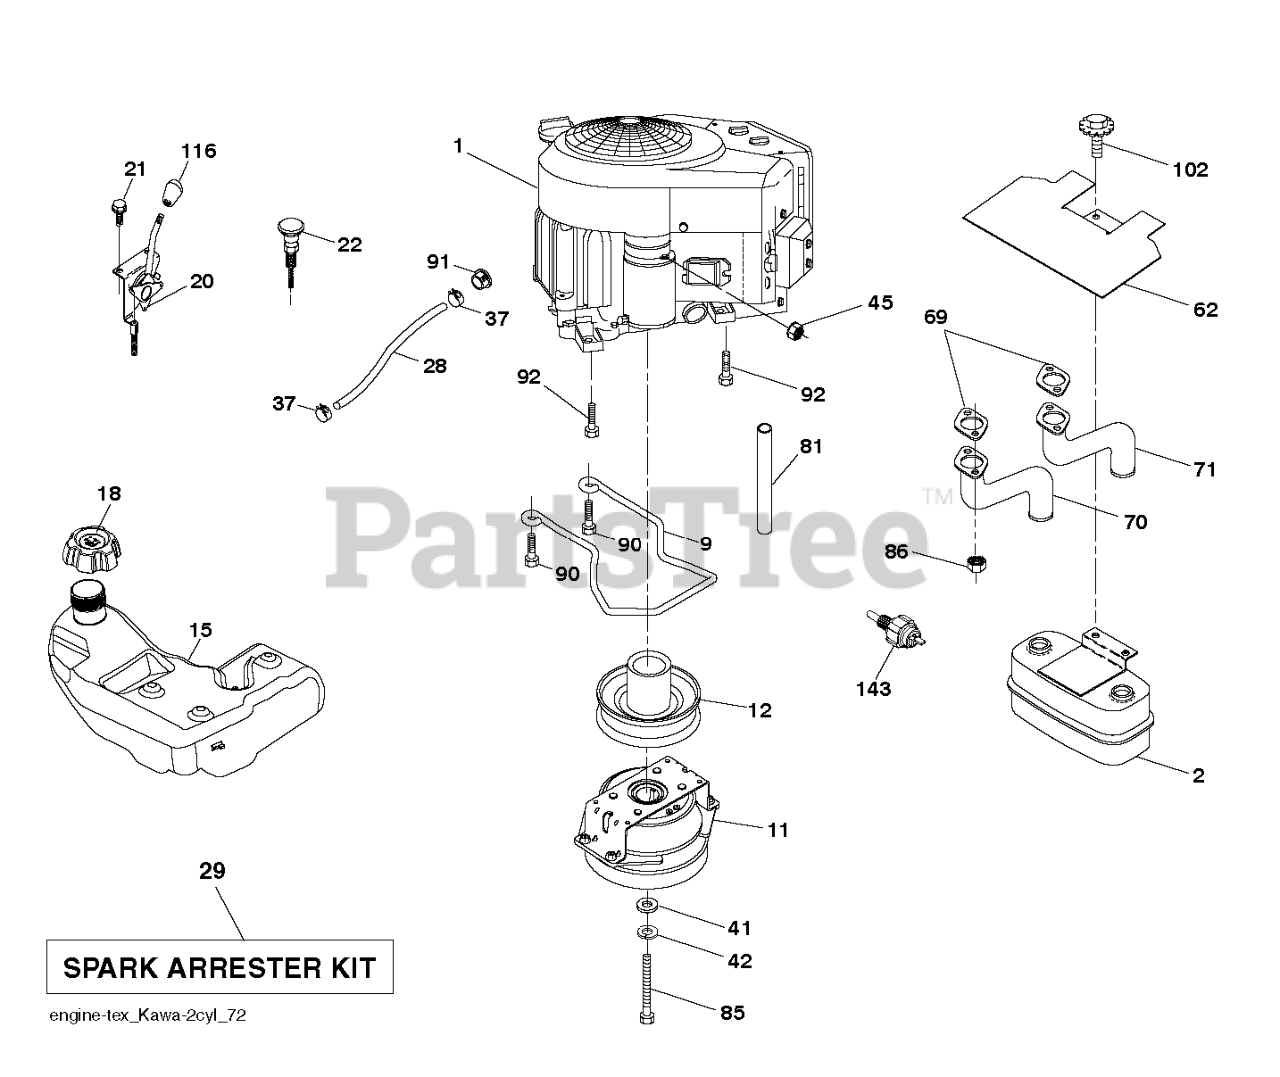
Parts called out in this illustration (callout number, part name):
2	MUFFLER.ASM.TWIN.MNTG.BRACKET
9	KEEPER.BELT.ENG.4.25"2.BLT.431
11	CLUTCH.OGURA.5.0PD.GT1.5A-EH01
12	PULLEY ENGINE
15	TANK.SUBASM.4GAL.2018
18	CAP ASSY FUEL 3" GRAY
20	CONTROL.THROTTLE.PRO.
21	SCREW.#10 X 0.750.BOS
22	CONTROL, CHOKE
28	LINE.FUEL.64"REAR.EMIS
29	KIT.SPARK ARRESTOR 794945 B&S
37	HOSE CLAMP
42	WASHER 7/16 LOCK
45	NUT
62	SHIELD.HEAT.MUFFLER
70	TUBE.EXHAUST.LH.FR961/FR730
71	TUBE.EXHAUST.RH.FR961/FR730
81	TUBE, DRAIN OIL ASM.
85	BOLT.HEX.7/16-20X3.GR5.YELLOW
86	NUT.HEX.FLANGE.TOPLOCK
90	SCREW 3/8-16X1
91	BUSHING.1.375OD
92	SCREW 3/8-16X1
102	SCREW
116	KNOB - SHIFT
143	SENSOR.SWITCH.PRESSURE.OIL
